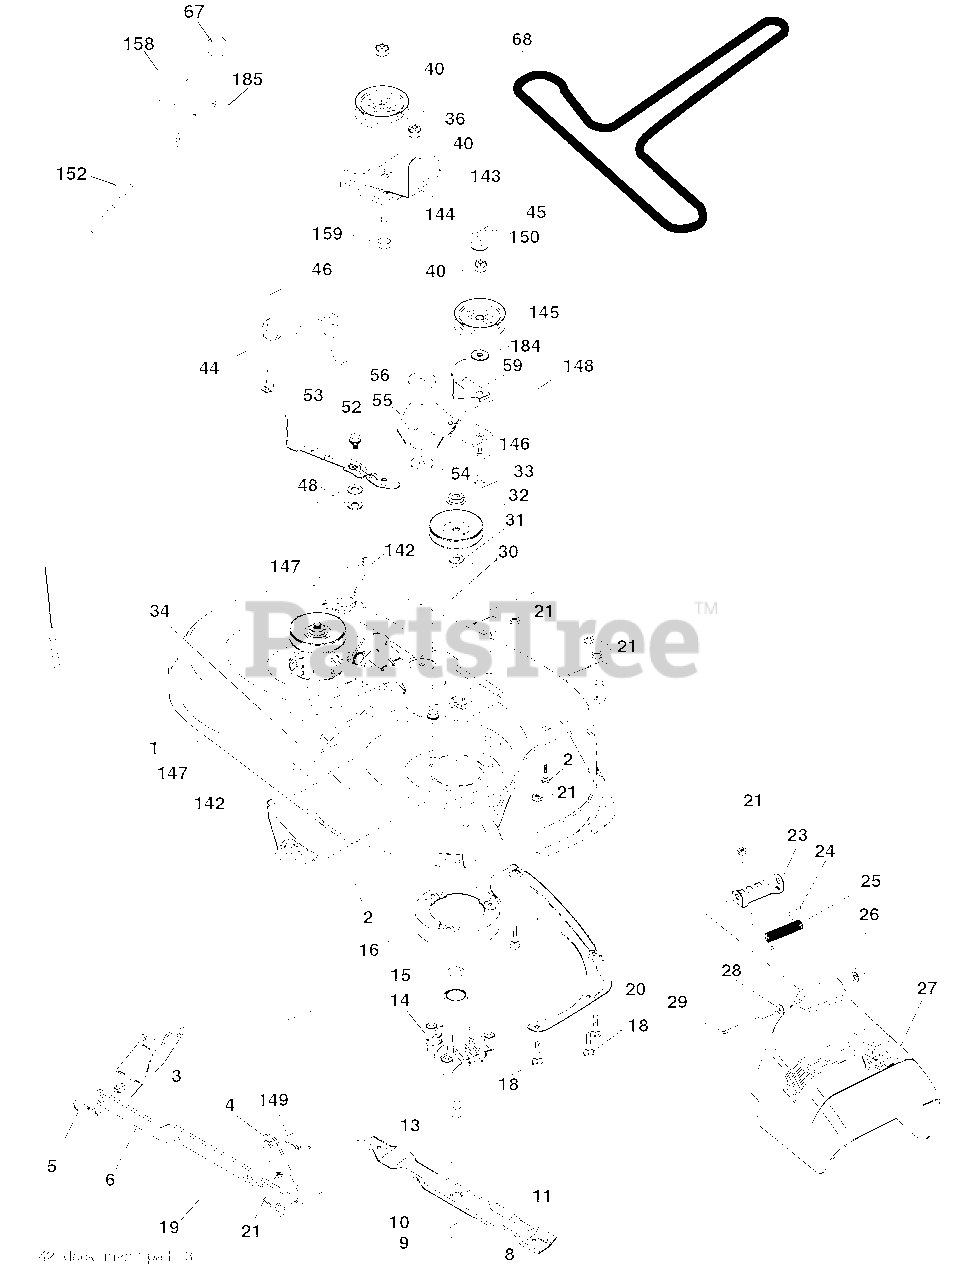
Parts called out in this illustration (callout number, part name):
1	Mower Deck Assembly, 42"
2	Bolt
3	Bracket Asm Fr. Sway Bar 3/42
4	Bracket Asm Deck 42" Sway Bar
5	Retainer Spring
6	Bar Sway Deck
8	Bolt 3/8-24 x 1.25 Gr. 8 patched
9	Washer, Lock
10	Washer, Hardened (The following Blades are available)
11	Blade Mower 42” Hi-Lift (for bagging and discharging)
11	Blade, Mulching 42” Std (for mulching mowers only)
11	Blade Mulching 42” Premium (For better wear when mulching)
13	Shaft As sem bly, Mandrel, Vented
14	Housing, Mandrel, Vented
15	Bearing, Ball, Mandrel
16	Stripper, Mandrel Deck
18	Bolt, Carriage 5/16-18 x 5/8
19	Bolt, Shoulder
20	Baffl e, Vortex
21	Nut
23	Bracket, Defl ector Mower 42"
24	Cap, Sleeve 80 x 112 Blk Mower
25	Spring, Torsion, Defl ector 2 52
26	Nut, Push Phos & Oil
27	Shield, Defl ector 42" Blk
28	Washer 11/32 x 5/8 x 16 Ga.
29	Rod, Hinge 42" 6 75 W/G
30	Screw Thdrol
31	Washer, Spacer Mower Vented
32	Pulley, Mandrel
33	Nut, Toplock
34	Bolt Carr SH 3/8-16 x 1-1/2 Gr.5
36	Pulley, Idler, Flat
40	Nut Lock 3/8-16
44	Guard, Mandrel, LH
45	Retainer
46	Screw, Thdrol 1/4-20 x 5/8 T
48	Washer, Hardened
52	Bolt, Shoulder 5/16-18 unc
53	Arm Assembly, Pad, Brake
54	Washer, Hardened
55	Arm, Idler
56	Spacer, Retainer
59	Guard TUV Idler
67	Knob Round
68	V-Belt, 42" Mower
142	Arm Spring Brake Mower
143	Bracket Arm Idler 42"
144	Keeper Belt 42" Clutch Cable
145	Pulley Idler Flat
146	Bolt Carriage Idler
147	Spring Extension
148	Spring Return Idler
149	Retainer Spring Yellow
150	Washer 9/32 x 3/4 x 10 Ga.
152	Clutch Cable 42"
158	Screw Hex Thd Cut 1/4-20 x 1/2
159	Bolt Rdhd Sqn 3/8-16 unc x 1-3/4
184	Washer 13/32 x 7/8 x 10 Ga.
185	Head Asm Cable Clutch
185	Mandrel Assembly
185	Replacement Mower, Complete
